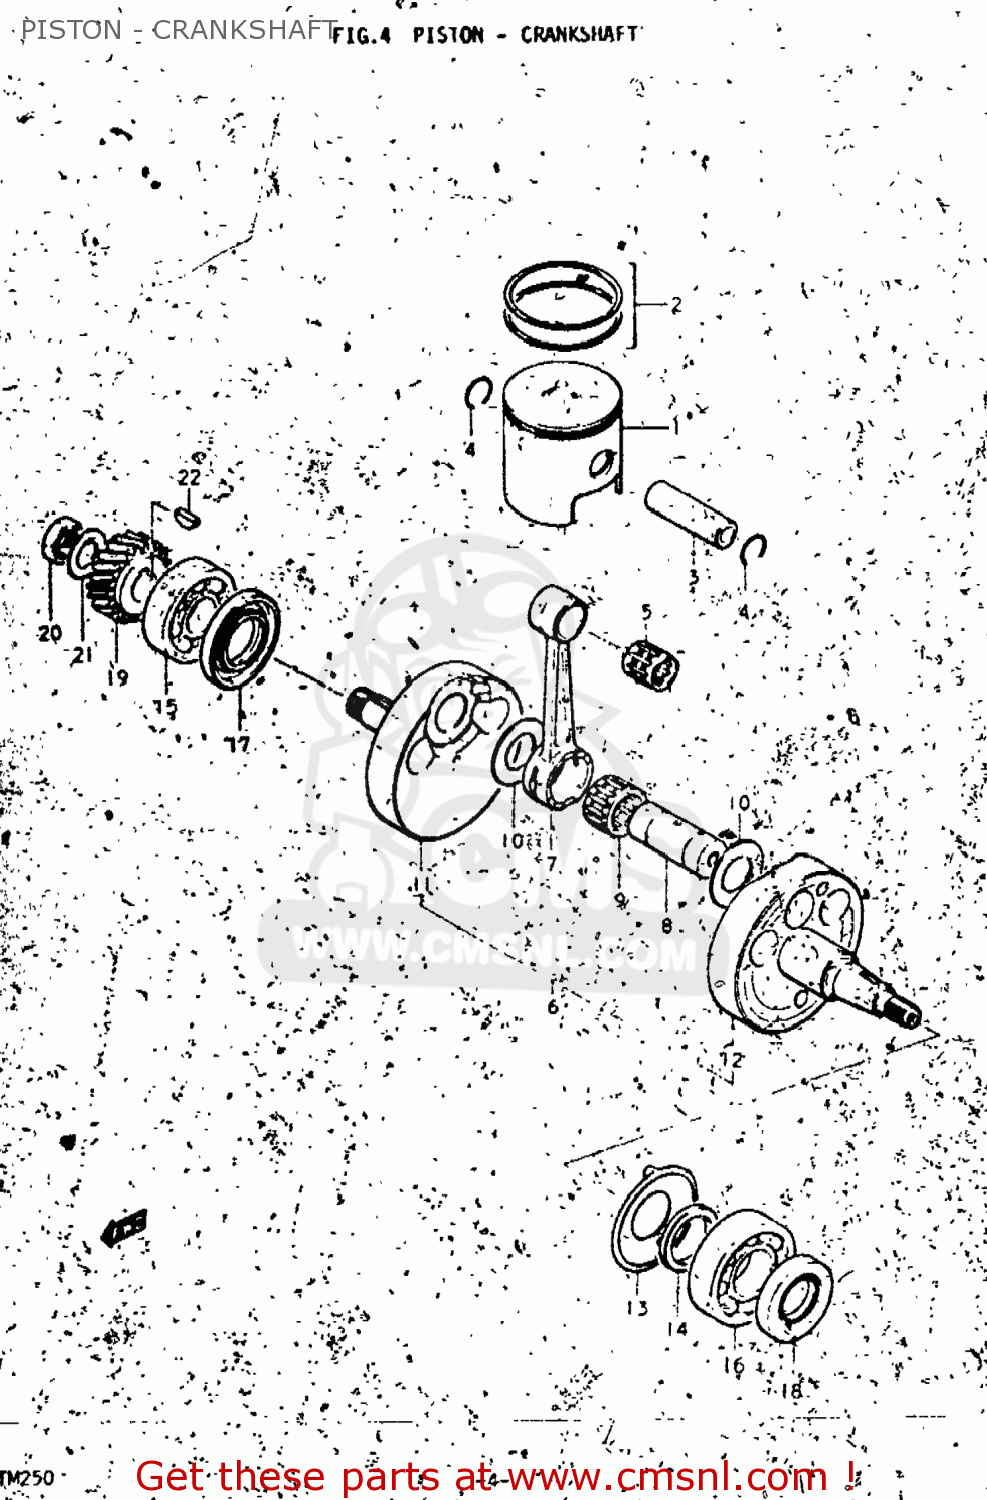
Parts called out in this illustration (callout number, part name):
1	PISTON
2	RING SET,PISTON
3	PIN,PISTON (18MM)
4	CIRCLIP
5	BEARING
6	CRANKSHAFT SET
7	ROD,CONNECTING
8	PIN,CRANK
9	BEARING(25X31X20)
10	WASHER
11	CRANKSHAFT
12	CRANKSHAFT,LEFT
13	PLATE,CRANKSHAFT OIL GUIDE
14	SPACER (30X45X4.8)
15	BEARING
16	BEARING(30X72X19)
17	SEAL,OIL(35X62X9)
18	OIL SEAL
19	GEAR,PRIMARY DRIVE
20	NUT
21	WASHER
22	KEY
